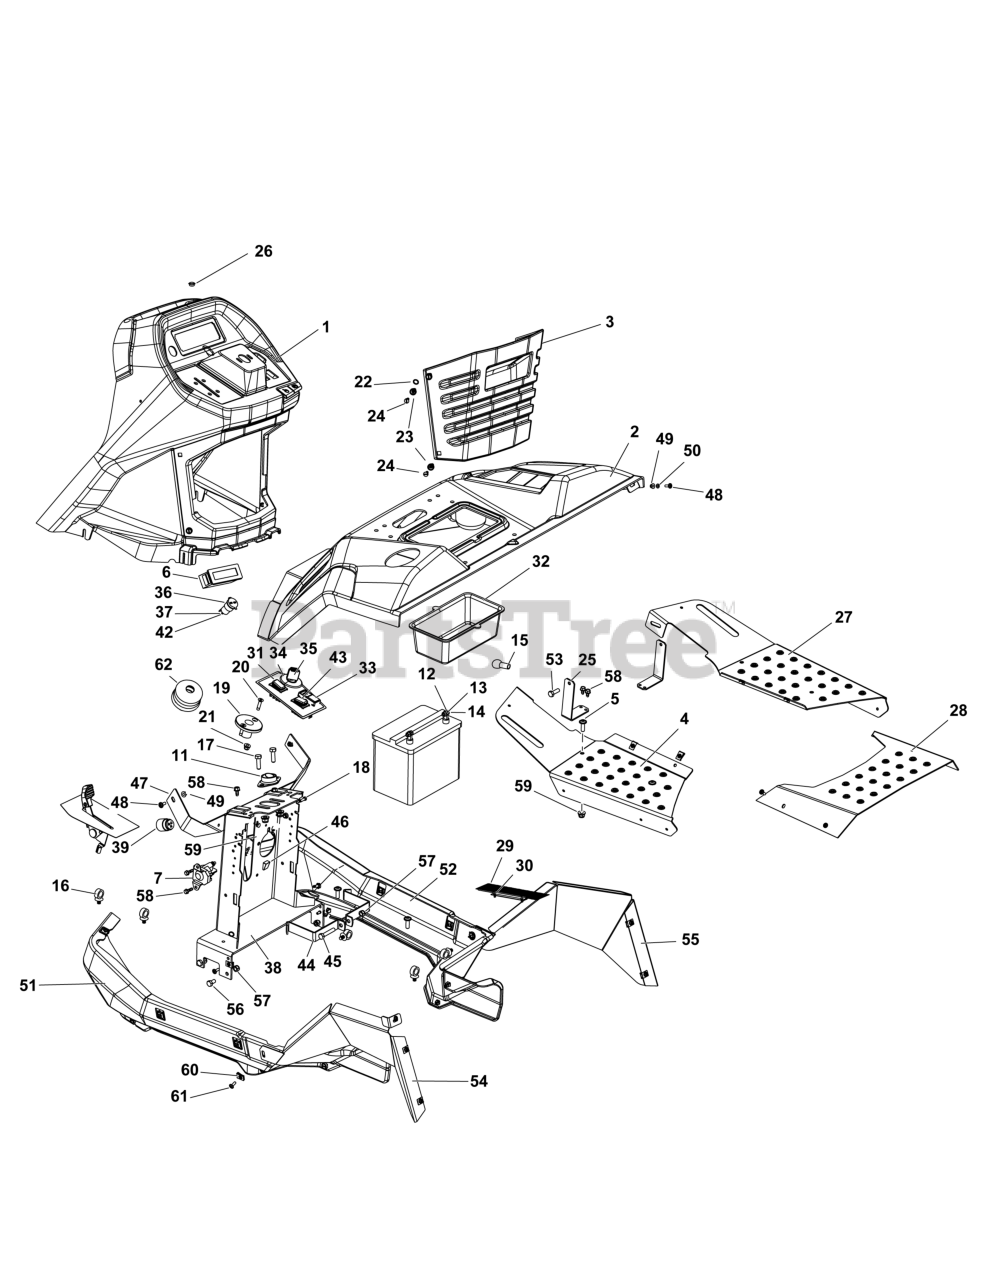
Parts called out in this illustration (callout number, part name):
1	PANEL, Dashboard
2	SEAT DECK
3	COVER, Battery
4	FOOTREST
7	SOLENOID
26	DAMPER, Rubber
27	PLATE, Floor
28	PLATE, Floor
29	COVER, Brush
35	KEY, Ignition
38	POST, Steering
54	FENDER, Left
55	FENDER, Right
